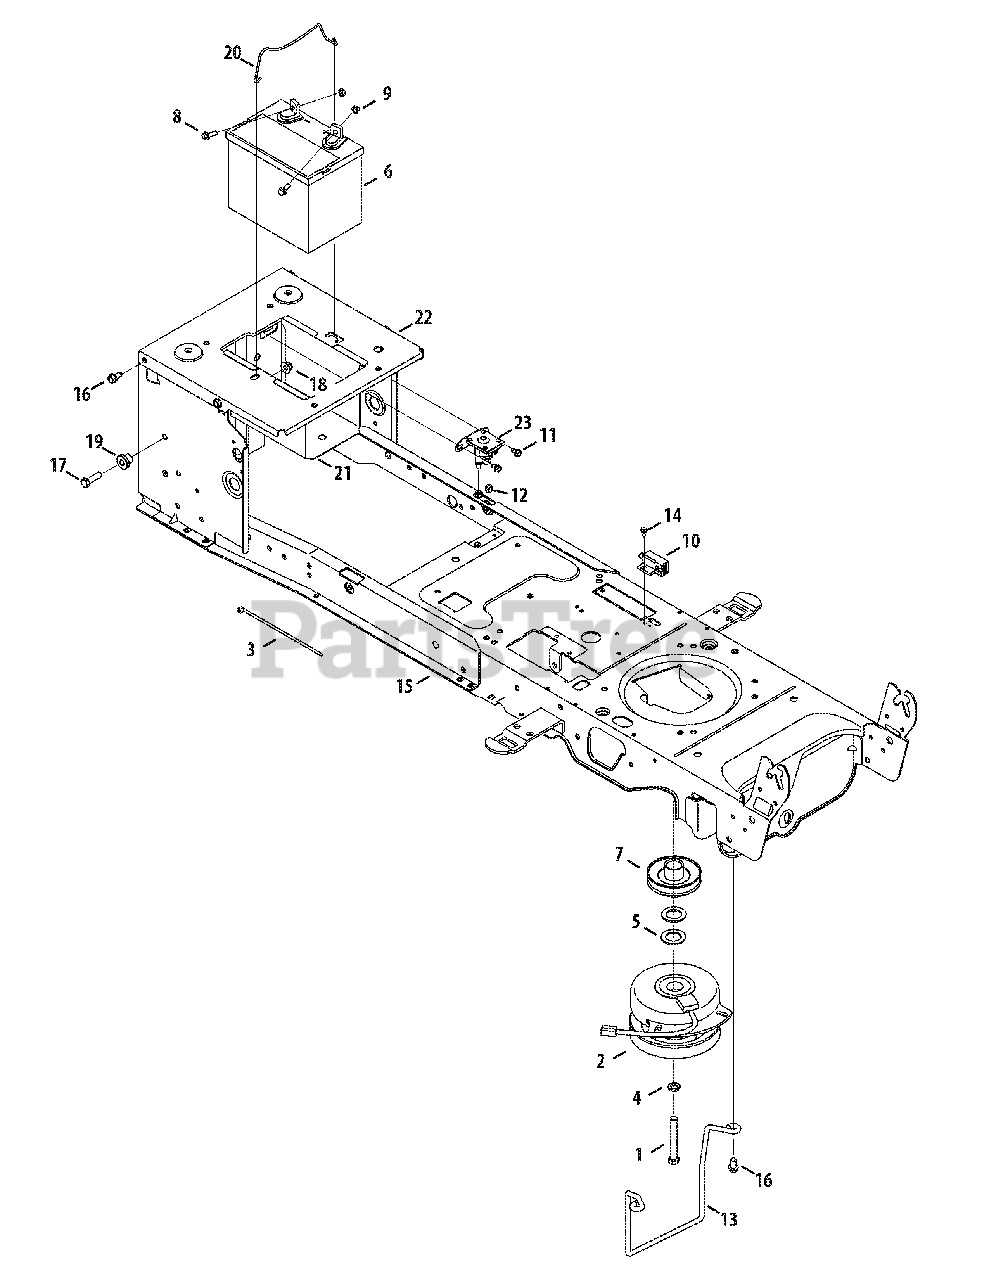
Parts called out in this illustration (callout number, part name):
1	Hex Screw, 7/16-20, 3.50, Gr5, Lock
2	Clutch, Electric PTO
3	Cable, Tie, 3/16 X .05 X 7.4
4	Washer, Lock, 7/16 , Regular Duty
5	Washer, Flat, 1.031 X1.620 X.095
7	Engine Pulley, Electric PTO
8	Hex Flange Screw, 1/4-20, .75, Gr5
9	Nut, Sems, 1/4-20
10	Switch, Interlock
11	Screw, Self-tapping, 1/4-20, 0.375
12	Nut, Flange Lock, 1/4-20, Nylon
13	Rod, Keeper (50")
14	Screw, Shoulder, #10-32, .50
15	Frame Assembly, Lower
16	Screw, Self-tapping, 5/16-18, .750
17	Hex Screw, 3/8-16, 1.25, Gr5, Std
18	Nut, Flange Lock, 3/8-16, Nylon
19	Spacer, Shoulder, .38 X 1.0 X .70
20	Rod, Battery
21	Tray, Battery
22	Bracket, Frame, Seat
23	Solenoid, 12V, 100 Amp, 4 term
